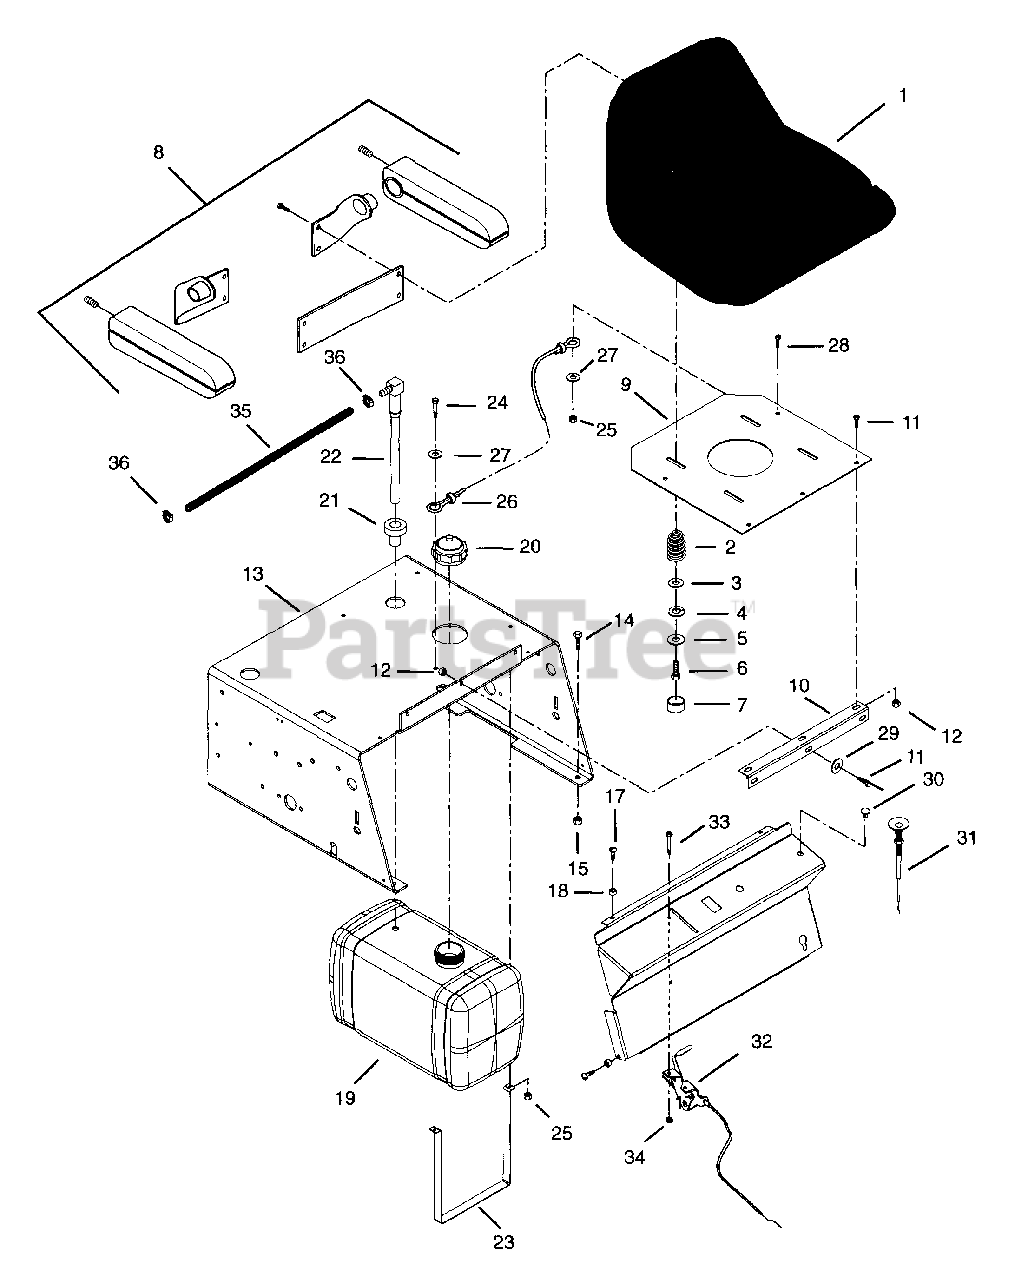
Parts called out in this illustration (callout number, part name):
2	SG-COMP .148X1.23X2.41 WLD87
3	WSHR-FL-STL.344X.688X.065PL
4	WSHR-LK .313X.078 PL MED
5	WSHR-FL-STL .380X.875X.179 PL
6	BLT-HEX .31-18X1.00 PL GR5
7	TUBE CAP
8	ARM REST KIT
9	SEAT PLATE
10	HINGE-2" X 12.88 YWZC
11	BLT-HEX .31-18X.75 PL GR5
12	NUT-LK-NYL.312-18 PL
13	SEAT SUPPORT
14	BLT-HEX .38-16X1.00 PL GR5
15	NUT-LK-NYL .375-16 PL
16	CONTROL PANEL
17	SCR-TAP 10-12X.62 CRPH PL A
18	PLASTIC GROMMET
19	FUEL TANK
20	FUEL CAP
21	BSHG-FLG .375 X 1.062 X .625 R
22	FITTING, TANK
23	STRP,FUEL TANK
24	BLT-HEX .25-20X2.00 FLLTHD GR5
25	NUT-LK-NYL .250-20 PL
26	SEAT CABLE
27	WSHR-FL-STL .328X1.0X.094 PL
28	BLT-HEX .25-20X.75 PL GR5
29	WSHR-FL-STL.344X.688X.065PL
30	HOLE PLUG, PLASTIC .44 HOLE
31	CONTROL,CHOKE
32	ASM, THROTTLE CONTROL
33	SCR-MCH 10-24X.50 PHD
34	NUT-LK 10-24 NY PL
35	HOSE, FUEL .25 ID X 22 LG
36	HOSE CLAMP
